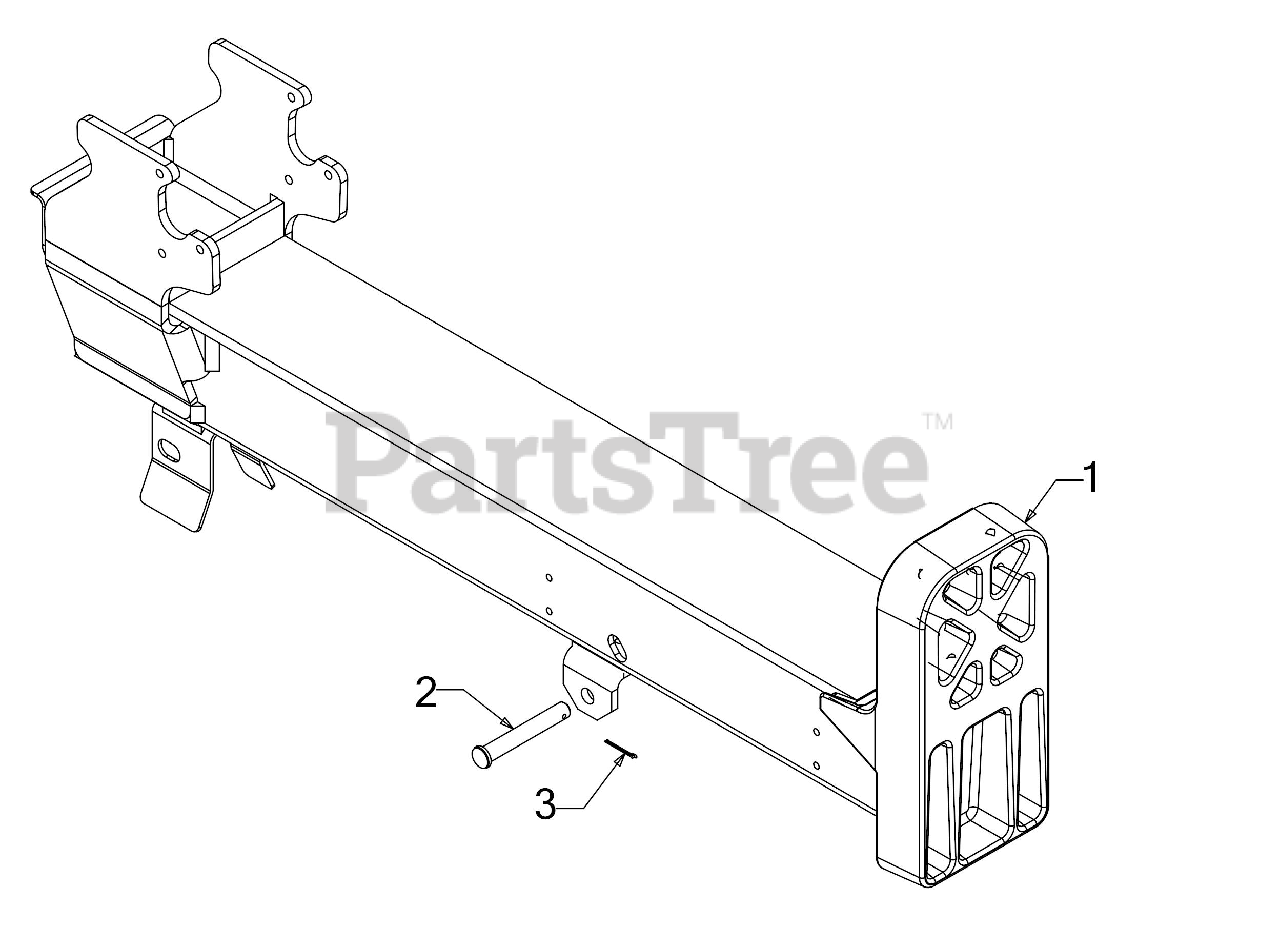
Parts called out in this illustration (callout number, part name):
1	BEAM ASSEMBLY
2	CLEVIS PIN .625 x 4.25
3	COTTER PIN
